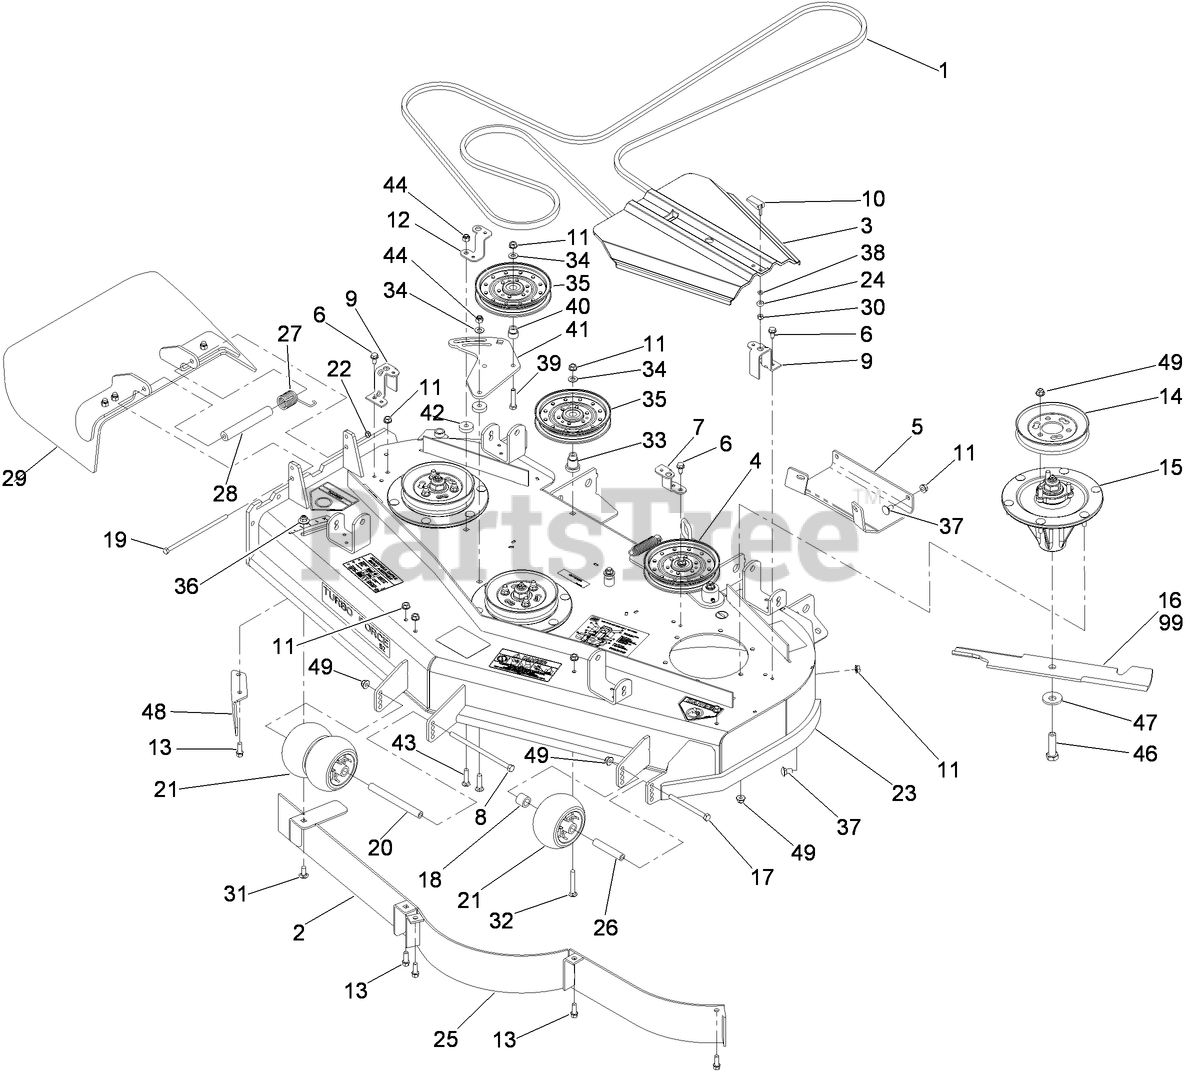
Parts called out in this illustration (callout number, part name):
1	BELT-V
2	BAFFLE ASM
3	COVER-BELT
4	SPRING IDLER ASM
5	Plate-Skid
6	SCREW-HWHTF
7	BRACKET-COVER, TALL
8	SCREW-HH
9	BRACKET-COVER
10	HANDLE-LATCH, SWELL
11	NUT-HHF, WHIZ
12	BRACKET-COVER, SHORT
13	SCREW-HWH
14	PULLEY
15	SPINDLE ASM
16	BLADE-18IN, HI FLOW
17	SCREW-HH
18	TUBE-SPACER
19	SCREW-HH
20	SPACER-WHEEL
21	ROLLER-SCALP, ANTI
22	NUT-LOCK, NI
23	DECK ASM
24	BUSHING-LATCH, SWELL
26	TUBE-SPANNER
27	SPRING-TORSION
28	SPACER
29	RUBBER DEFLECTOR ASM
30	NUT-LOCK, HH
31	SCREW-CARR
32	SCREW-CARR
33	MOUNT-PULLEY
34	WASHER-FLAT
35	Idler-Flat
36	NUT-FLANGE, NI
37	SCREW-CARR
38	WASHER
39	SCREW-HH
40	BUSHING-IDLER
41	PLATE-IDLER
42	Spacer
43	SCREW-CARR
44	NUT-LOCK, NI
46	SCREW-BLADE
47	Washer-Blade Bolt, Heavy
48	BAFFLE-DISCHARGE
49	NUT-HF, NI
99	BLADE-MED FLOW
99	BLADE-RECYCLER
99	BLADE-LOW FLOW
99	BLADE-ATOMIC
